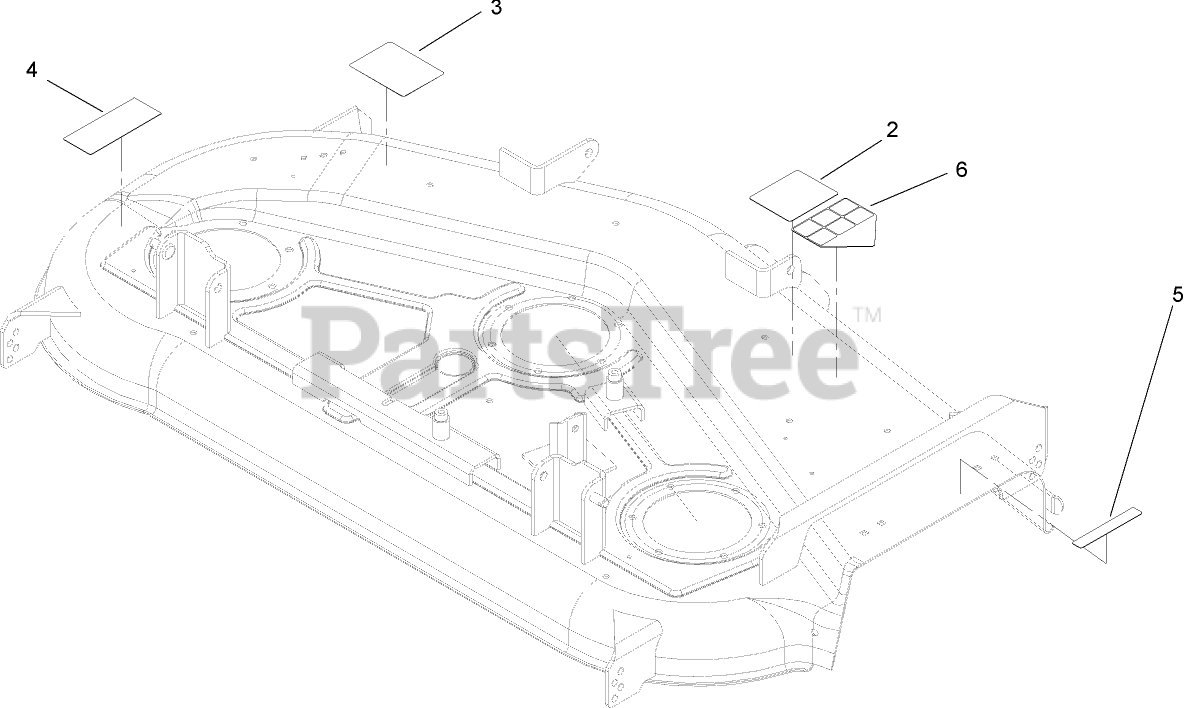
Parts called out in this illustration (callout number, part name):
2	DECAL-ROUTING, BELT
3	DECAL-ANTI SCALP
4	DECAL-DANGER
5	DECAL-DANGER
6	DECAL-DANGER
